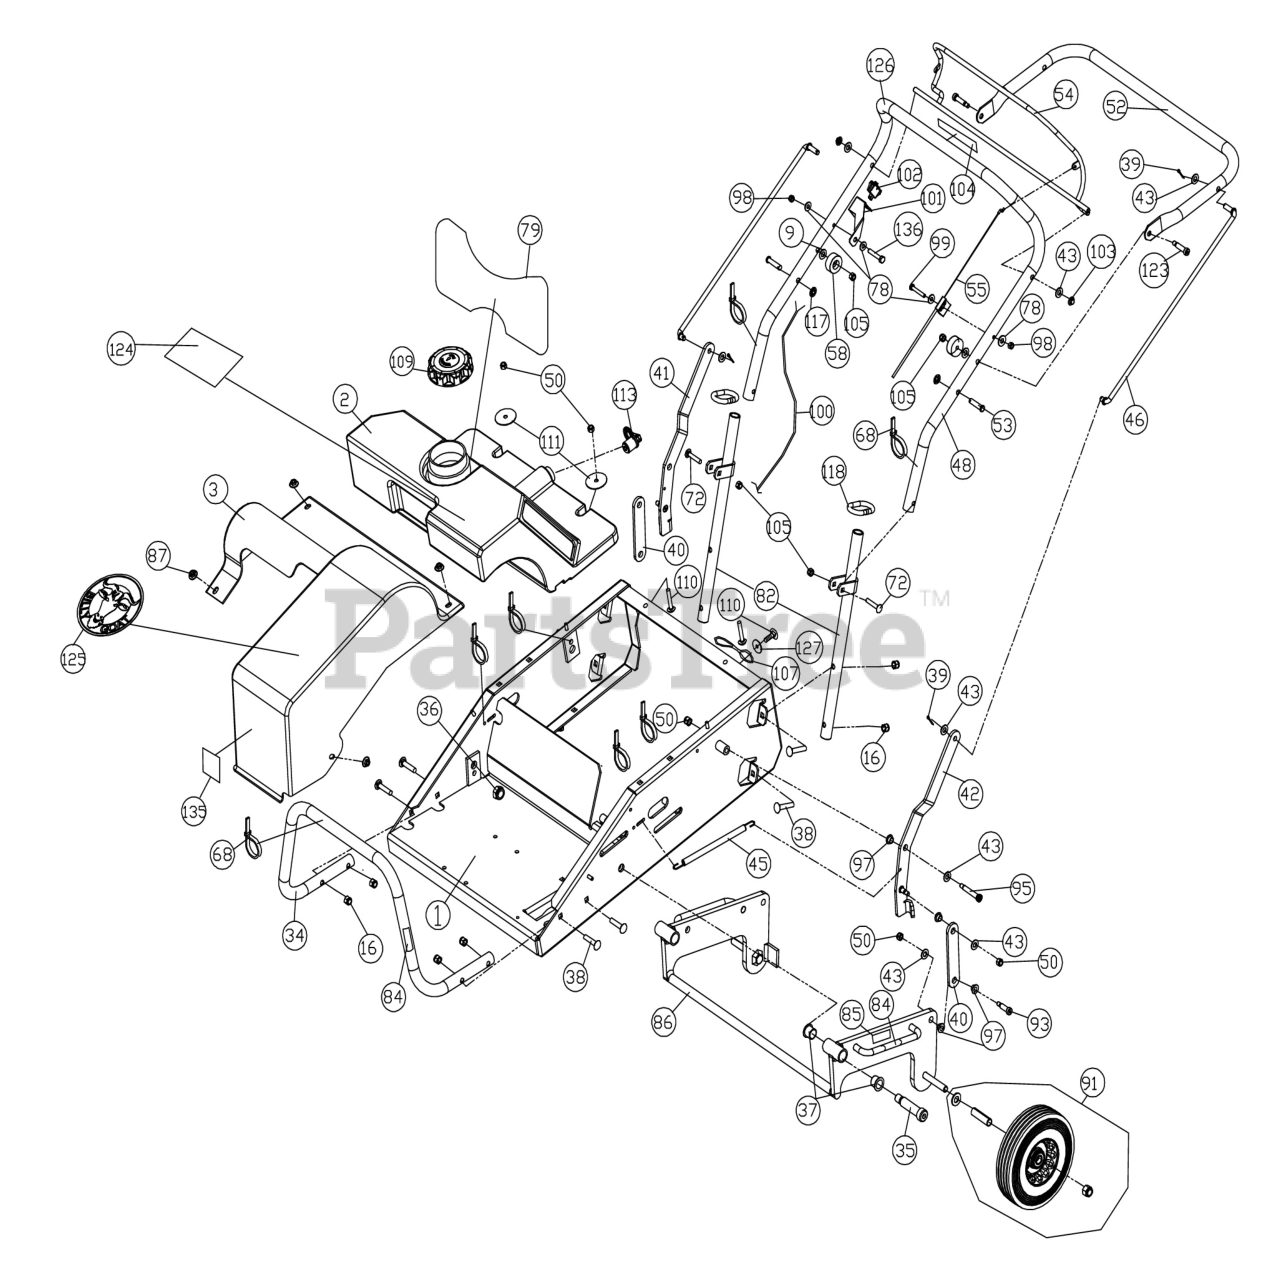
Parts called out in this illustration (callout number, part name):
1	FRAME WA AE401
2	SEE: 360238-S
3	COVER, DRIVE UNIVERSAL AE401
9	WASHER FLAT FENDER 5/16
16	NUT-HEX-NYLK, FLG .375"-16 ZP
34	TUBE FRONT BUMPER AE401
35	BOLT SHOULDER 3/4 X 2 1/2
36	NUT LOCK 5/8"-11 LT WT TH Z/P
37	BUSHING PIVOT FRAME AE
38	BOLT CARRIAGE 3/8"-16 X 1 3/4" ZP
39	PIN COTTER 1/8" X 1" Z/P
40	PLATE LINKAGE SHORT AE4
41	PLATE LINKAGE RH LONG WA AE401
42	PLATE LINKAGE LH LONG WA AE401
43	WASHER 3/8"SAE 13/32"X13/16"X1/16"
45	SPRING EXTENSION AE
46	ROD LIFT SIDE AE4
48	HANDLE UPPER RENOVATION
50	NUT-HEX-NYLK, FLG .3125-18 ZP
52	HANDLE LIFT
53	PIN CLEVIS 3/8 X 1.625
54	BAIL WA RENOVATION
55	CABLE CLUTCH ASSY AE401
58	BUMPER RECESS
72	BOLT CARRIAGE 5/16"-18 X 1 3/4" ZP
78	WASHER 1/4"SAE9/32"X5/8"X1/16"
79	SEE: 360505
82	HANDLE LOWER WA AE4
84	LABEL LIFT HERE
85	LABEL WARNING WEIGHT AE
86	FRAME REAR WA AE4
87	NUT LOCK 1/4"-20 WASH FACE
91	TIRE & WHEEL 8" X 1/2" I.D. KIT
93	BOLT SHOULDER 3/8 X 1"
95	BOLT SHOULDER 3/8" X 2"
97	BUSHING LIFT AE
98	NUT-HEX-NYLK, FLG .250"-20 ZP
99	SCREWCAP 1/4"-20X1 3/4" HCS ZP
100	HARNESS WIRE 60"
101	BRACKET MOUNT SWITCH QB16SP
102	SWITCH LKG RKR B&S #493521
104	LABEL CLUTCH VQ
105	NUT LOCK 5/16"-18 LT WT TH ZP
107	LANYARD PLASTIC 10"
109	CAP WATER TANK
110	SCREW SELF TAP 1/4"-20 X 5/8" HWH TYPE F
111	WASHER EXTENSION
113	PLUG DRAIN 1"
117	RETAINER 3/8" BOLT PUSH NUT
118	LOOP FOLDING HANDLE PR
123	BOLT SHOULDER 3/8" X 1 1/4"
124	LABEL BADGING AE401
125	LABEL ROUND LOGO 3.5"
126	GRIP HANDLE 1" X 13" FOAM
127	WASHER FLAT FENDER 1/4"
135	BOLT CARRIAGE 5/16"-18 X 2" ZP
136	SCREWCAP 1/4"-20X1 1/2" HCS ZP
137	BOLT CARRIAGE 5/16"-18 X 2" ZP
